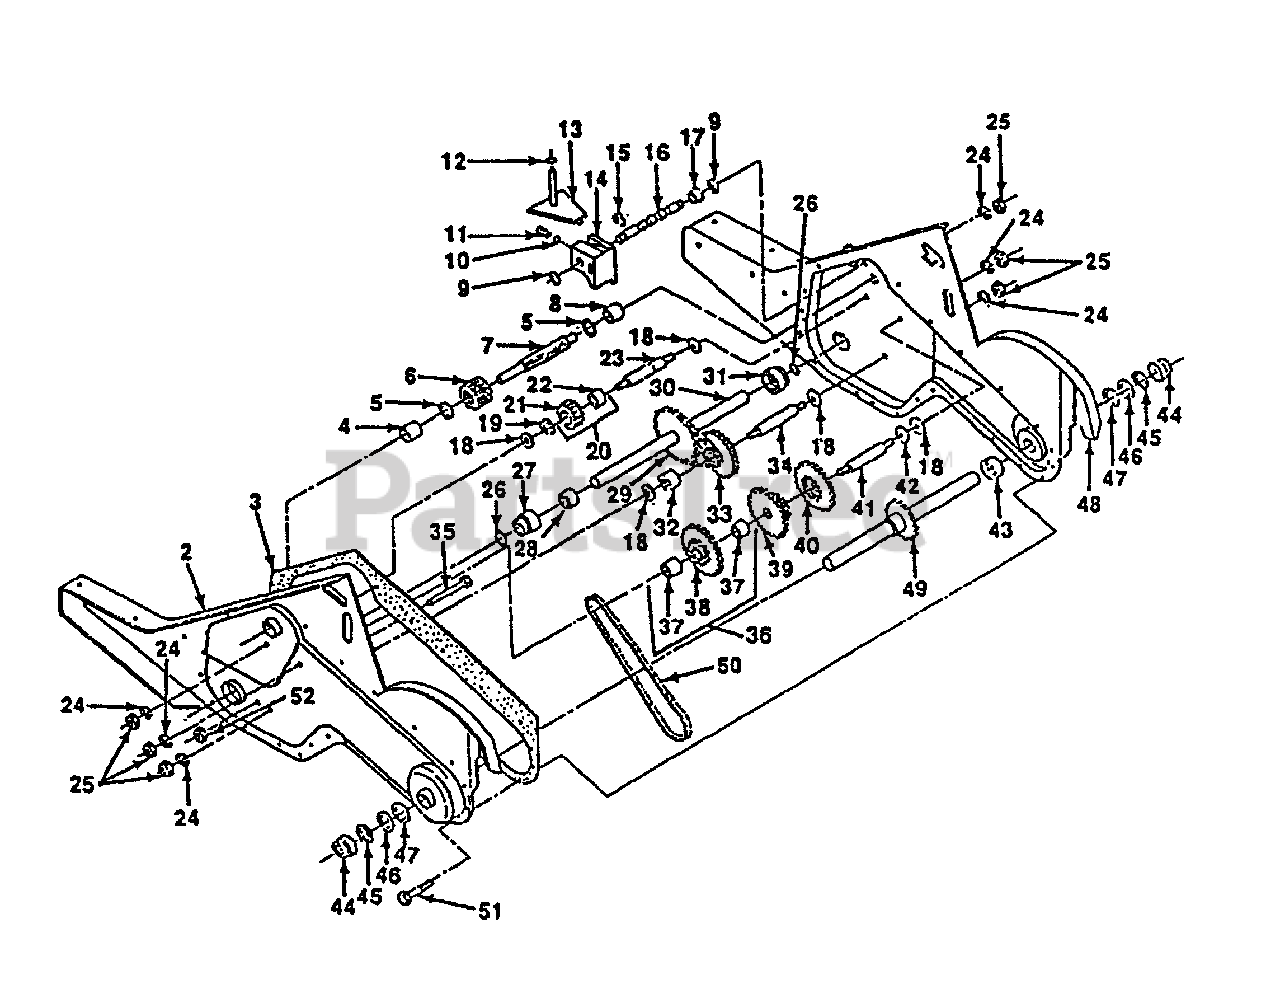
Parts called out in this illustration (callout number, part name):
2	Gearcase, L.H. w/Bearing
3	Gasket, Gearcase
4	Bearing, Needle
5	Washer, Thrust 5/8 x 1.10 x 1/32
6	Pinion, Input
7	Shaft, Input
8	Bearing, Needle
9	Washer, Seal
10	Ball, Steel
11	Spring, Shift, Fork
13	Arm, Shift
15	Ring, Klip
16	Shaft, Shift
17	Spacer, Split
19	Ring, Klip
20	Gear, Assembly, Reverse Idler
21	Gear, Reverse Idler
22	Bearing, Needle
23	Shaft, Reverse Idler
24	Washer, Lock 7/16
25	Nut, Hex 7/16-20
27	Bearing, Shaft, Ground Drive
28	Spacer 0.765 x 1.125 x 1.23
29	Chain #35-50 Pitch
30	Ground Shaft Assembly
31	Bearing, Shaft, Ground Drive
32	Spacer 0.70 x 1.00 x 1.150
33	Sprocket and Gear Assembly
34	Shaft, Reduction (2nd)
35	Screw, Whiz, Lock 5/16-18 x 3-1/2
36	Sprocket Assembly w/Bearing
37	Bearing, Needle
38	Sprocket, Tine
39	Gear, Cluster, Red 1st & 2nd
40	Gear, Reverse
41	Shaft, Reduction (1st)
42	Washer, Thrust
43	Spacer 1.01 x 1.75 x 0.760
44	Cup, Formed
45	Ring, Spiral
46	Seal, Ring, Rubber
47	Seal, Oil
48	Gearcase, R.H. w/Bearing
49	Shaft, Tine
50	Chain, Roller #50-50 Pitch
51	Screw 1/4-20 x 1/2
52	Nut, Hex 5/16-18
